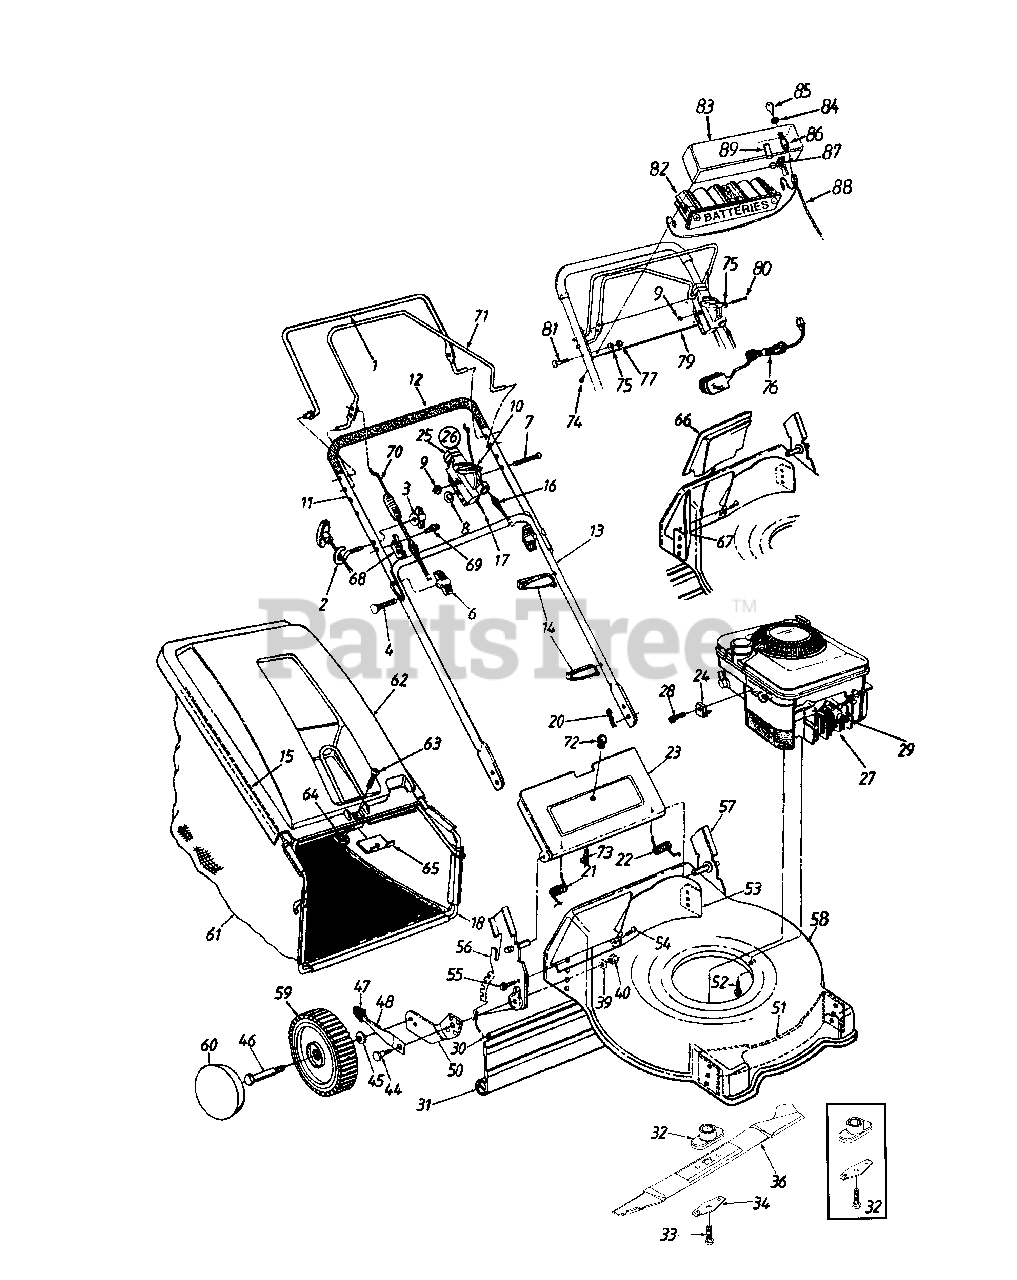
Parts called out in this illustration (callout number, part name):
2	Rope Guide
3	Handle Knob 1/4-20 Thd.
4	Curved Hd. Bolt 5/16-18 x 2" Lg.
6	Hand Knob
7	Oval C-Sunk Mach. Scr.
8	Spr. Wash. .66" I.D.
9	Hex L-Nut 1/4-20 Thd.
10	Throttle Lever
14	Cable Tie
16	Control Cable-39" For model (450)
16	Control Cable-36" For model (456, 458)
16	Control Cable-51" For model (455)
17	Throttle Control Wire-42" For model (455)
17	Throttle Control Wire-55" For model (450,456, 458)
21	Door Spring-R.H.
22	Door Spring-L.H.
24	Cable Clamp (B&S)
25	Throttle Body
26	Throttle Box Comp. (Incl Ref. 7, 8, 9, 10, 25)
27	Engine
28	Hex Sems Scr. #10-32 x .38" Lg. (Tec.)
28	Hex Wash. Hd. Scr. #10-32 x .62" Lg. (B&S)
29	Spark Plug Boot (Optional)
30	Wire Rod
31	Rear Flap
32	Blade Adapter Kit
33	Hex Bolt 3/8-24 x 1.5" Lg.
34	Blade Bell Support
36	21" Blade
36	21" Mulching Blade (Optional)
39	Bell-Wash. .39" I.D. x 1.38"
40	Hex Nut 3/8-16 Thd.
44	Shld. Bolt .5" Dia. x .357"
45	Bell-Wash. .38" I D. x .88" O.D.
46	Axle Bolt
47	Spring Lever Knob
48	Spring Lever
50	Pivot Bar
54	Torx Mach. AB-Tap Scr. 1/4 x .62" Lg.
55	Hex L-Wash. Hd. AB-Tap Scr. 1/4 x .62" Lg.
56	Handle Brkt. Ass'y.-R.H.
57	Handle Brkt. Ass'y.-L.H.
60	Hub Cap 3-1/2" Dia. (Gray) (Optional)
60	Hub Cap 5-1/2" Dia. (Gray) (Optional)
60	Hub Cap 5-1/2" Dia. (Beige) (Optional)
61	Grass Bag
62	Hard Top Cover
63	Pan Hd. Mach. Scr. 1/4-20 x .5"Lg.
64	Hex Nylon L-Nut 1/4-20 Thd.
68	Cable Mtg. Brkt.
69	Hex Wash. AB-Tap Scr. 5/16" x .75" Lg.
70	S.P. Cable 44.75" Lg.
73	Truss Mach. Scr. #10-24 x .38" Lg.
74	Pan Hd. Scr. #12 x 3/4" Lg.
75	Bell-Wash. 1/4" I.D.
76	Charger
77	Hex Nut 1/4-20 Thd.
78	L-Wash. 1/4" I.D.
81	Curved Hd. Bolt 1/4-20 x 1.25" Lg.
82	Battery Pack
83	Upper Battery Tray
84	Key Switch
85	Key
86	Fuse Holder
87	Plug
88	Harness
89	Fuse 7-1/2 Amp
